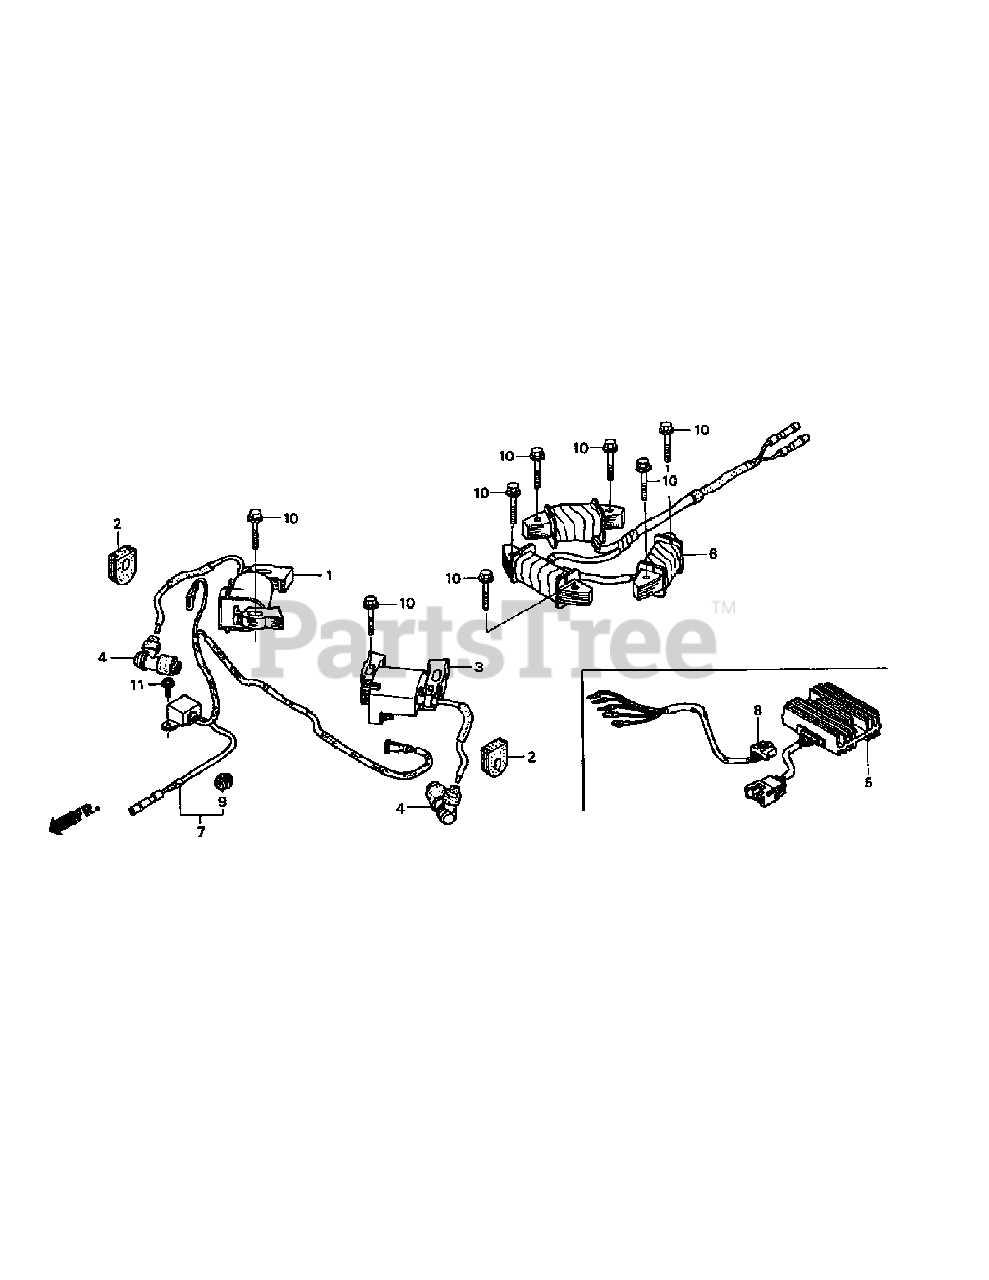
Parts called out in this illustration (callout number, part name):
1	Ignition Coil Assy. R.H.
2	Ignition Wire Grommet
3	Ignition Coil Assy. L.H.
4	Noise Suppressor Cap Assy.
5	Voltage Regulator
6	Stator Assy.
7	Engine Stop Diode Assy.
8	Sub-Wire Harness Assy.
10	Flange Bolt (6x32)
11	Flange Bolt (6x8)
